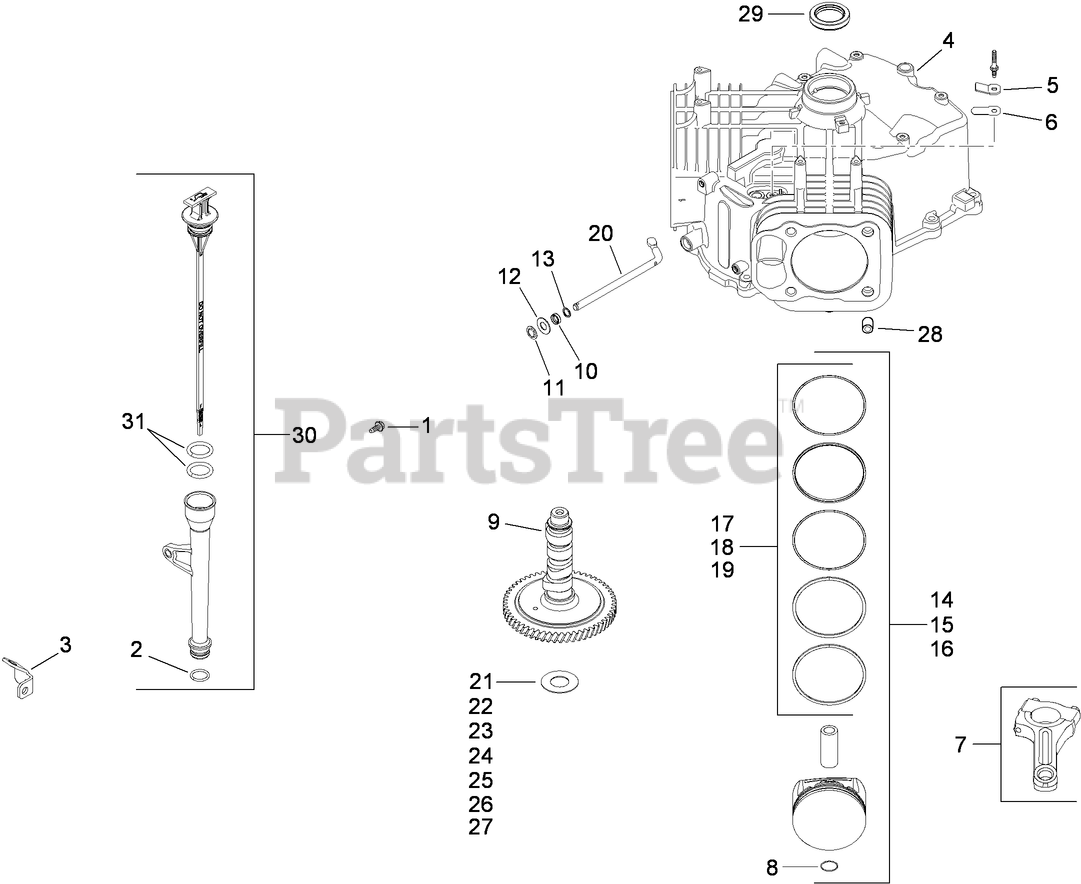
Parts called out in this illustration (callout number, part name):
1	SCREW-FLG, THD FRM (M5X0.8X13)
2	O-RING
3	BRACKET-TUBE, OIL FILL
4	SHORTBLOCK (SV710-740)
5	RETAINER-REED, BREATHER
6	REED-BREATHER
7	ROD-CONNECTING (STD)
8	RETAINER-PIN, PISTON
9	CAMSHAFT KIT (INCLUDES 25 357 14-S)
10	SEAL-CROSS SHAFT, GOVERNOR
11	RETAINER-RING
12	WASHER-FLAT (9MM)
13	WASHER-FLAT (11/32)
14	PISTON W/RING SET (STD) (INCLUDES REF 8, 17)
15	PISTON W/RING SET (.08) (INCLUDES REF 8, 18)
16	PISTON W/RING SET (.25) (INCLUDES REF 8, 19)
17	PISTON RING SET (STD)
18	PISTON RING SET (.08)
19	PISTON RING SET (.25)
20	SHAFT-CROSS, GOVERNOR
21	SHIM-CAMSHAFT (WHITE .028)
22	SHIM-CAMSHAFT (BLUE .03)
23	SHIM-CAMSHAFT (RED .032)
24	SHIM-CAMSHAFT (YELLOW .034)
25	SHIM-CAMSHAFT (GREEN .036)
26	SHIM-CAMSHAFT (GRAY .038)
27	SHIM-CAMSHAFT (BLACK .04)
28	PIN-LOCATING
29	SEAL-OIL (HELIX LIP)
30	DIPSTICK AND TUBE ASM (INCLUDES REF 2, 31)
31	O-RING
